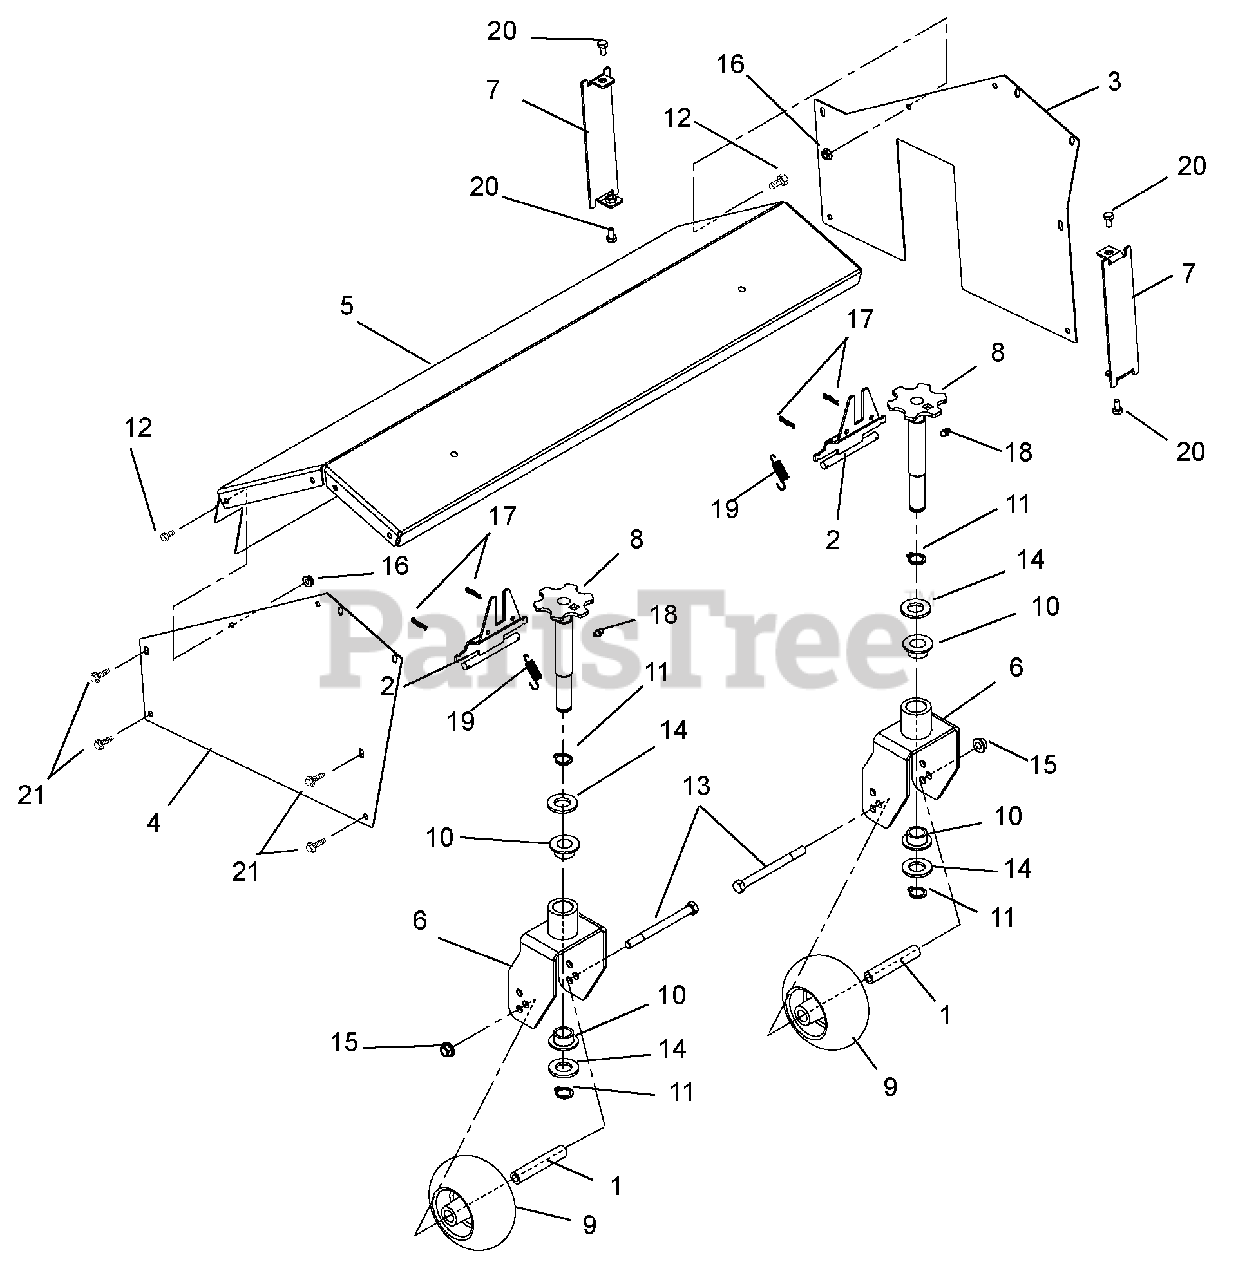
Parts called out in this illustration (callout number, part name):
1	SPACER, CASTER WHEEL
2	LOCK,CASTER HEIGHT
3	COVER,LH SIDE BRUSH
4	COVER,RH SIDE BRUSH
5	COVER WITH DECALS, 28"BRUSH
6	CASTER FORK, BRUSH
7	COVER,END
8	HEIGHT ADJUSTER, CASTER
9	WHEEL, ANTI SCALP
10	BSHG-FLG .762X1.0X.580X1.48 NY
11	RG-RTNG-EXT .689X.078
12	@BLT-HEX .25-20X.50 GR5 YWZC
13	@BLT-HEX .38-16X4.50 GR5 YWZC
14	@WSHR-FL-STL.812X1.50X.135YWZC
15	@NUT-LK-TOP-FLG .38-16 YWZC
16	@NUT-LK-TOP-FLG .25-20 YWZC
17	PIN-HAIR, ENDRIES #25 YWZC
18	FTG-LUBE .25-28X.256 YWZC
19	SPRING-EXT .047 X .438 X 1.85
20	@BLT-HEX .25-20X.50 GR5 YWZC
21	@SCR-TAP .25-20X.50 HWH TR YWZ
